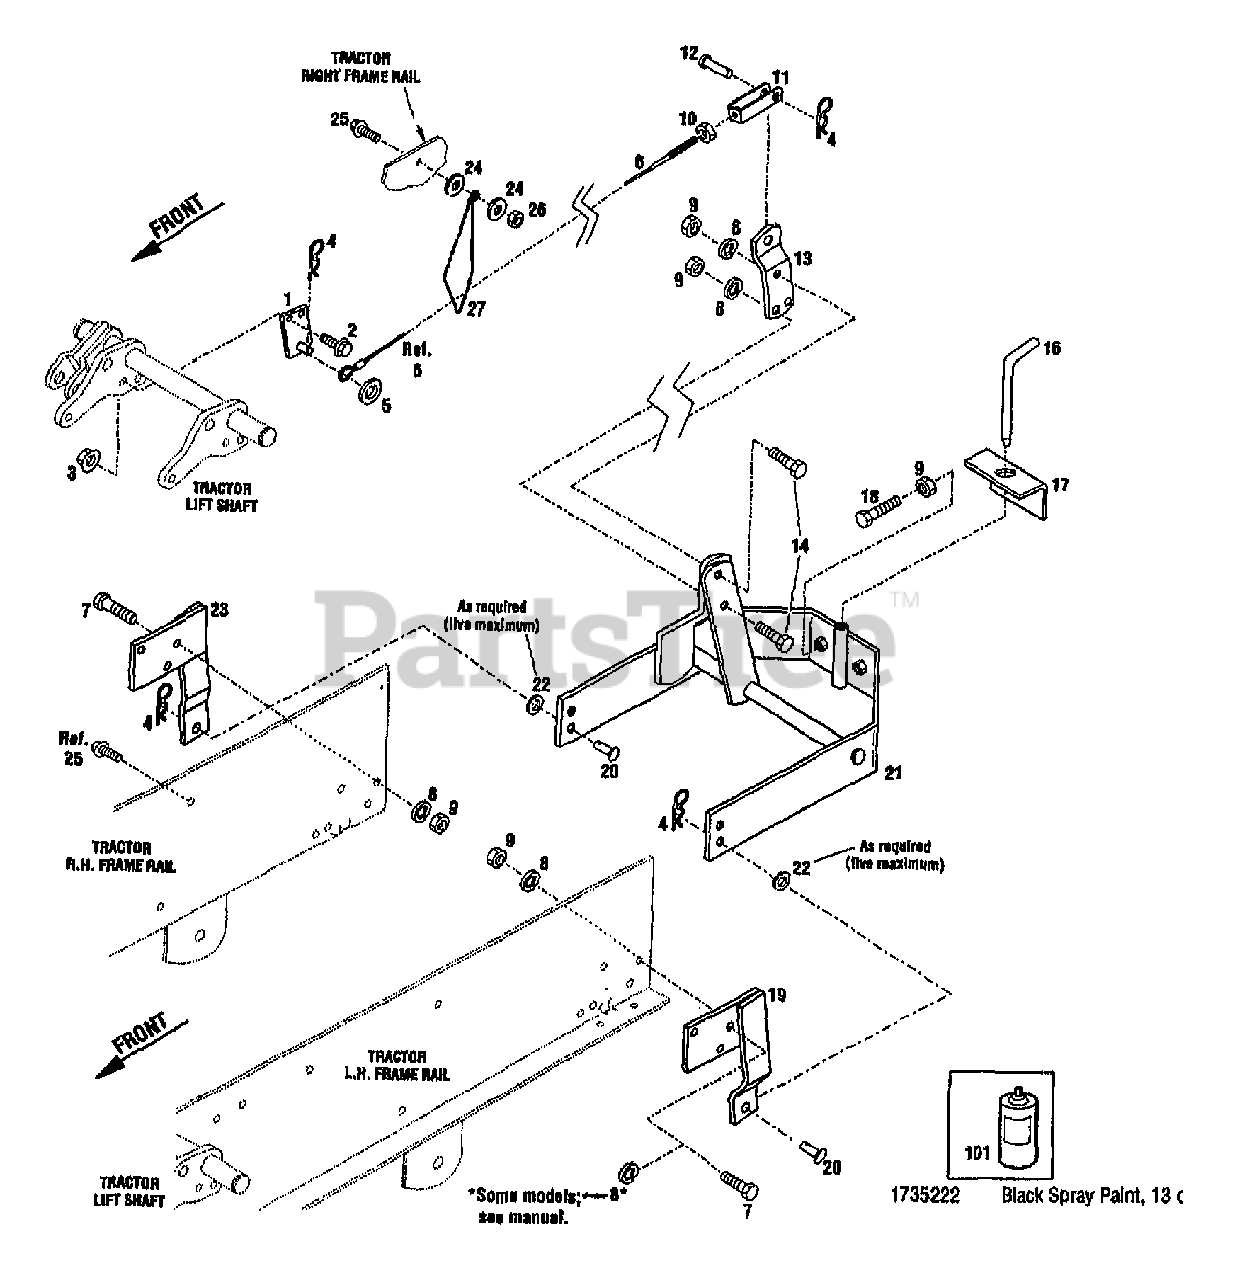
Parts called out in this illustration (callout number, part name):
2	SCR-HFLK 3/8-16X1.00 ZP
3	NUT-HFLK 3/8-16 ZP
4	PIN-HITCH .125X2.56 ZP
5	WASHER-1.06X.531X.1 ZP
6	CABLE-LIFT
7	SCR-HH 1/2-13X1.25 G5 ZP
8	WASHER-LK .5
9	NUT-HEX JAM 1/2-13
10	NUT-HEX/JAM 3/8-16
11	YOKE-CABLE
12	PIN-CLEVIS .5X1.25
14	SCR-HH 1/2-13X1.5 G5 ZP
16	PIN-HITCH .625 DIA
17	PLATE-STABLIZER
18	SCR-HH 1/2-13 X 2.00
19	ARM-HITCH LH
20	PIN-CLEVIS
21	HITCH-SLEEVE F/GARDEN TRAC
22	WASHER-1.305X.649X.098 ZP
23	ASSM-ARM HITCH RH
24	WASHER-.875X.390X.134
25	SCR-HFLK 3/8-16X1.25 ZP
26	NUT-H/LK 3/8-16
27	GUIDE-CABLE
101	PAINT-BLACK SPRAY
